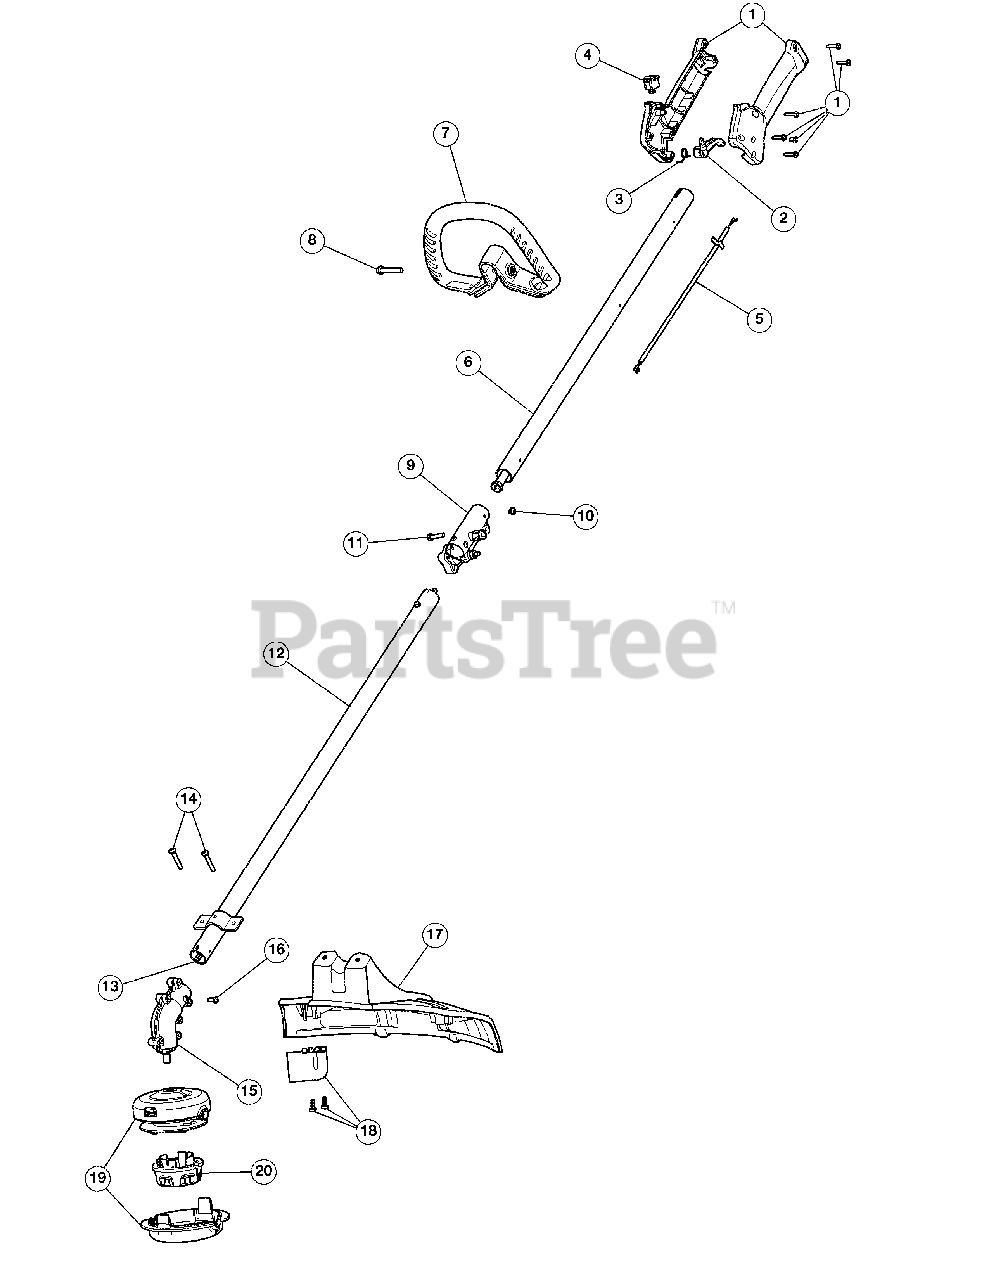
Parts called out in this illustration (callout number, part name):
1	Throttle Housing Assembly (Incl. 2-4)
2	Throttle Trigger
3	Throttle Trigger Spring
4	Switch Assembly
5	Throttle Cable Assembly
6	Upper Drive Shaft Assembly
7	D-Handle Assembly (Incl. 8)
9	Split Boom Coupler (Incl. 10-11)
10	Coupler Anti-Rotation Screw
11	Coupler Hardware
12	Lower Drive Shaft Housing
13	Lower Flexible Drive Shaft
14	Shield Mount Screw Assembly
15	Gearbox Assembly (Incl. 16)
17	Shield Assembly (Incl. 18)
18	Blade Assembly
19	Cutting Head Assembly (Incl. 20)
20	Bump Knob
